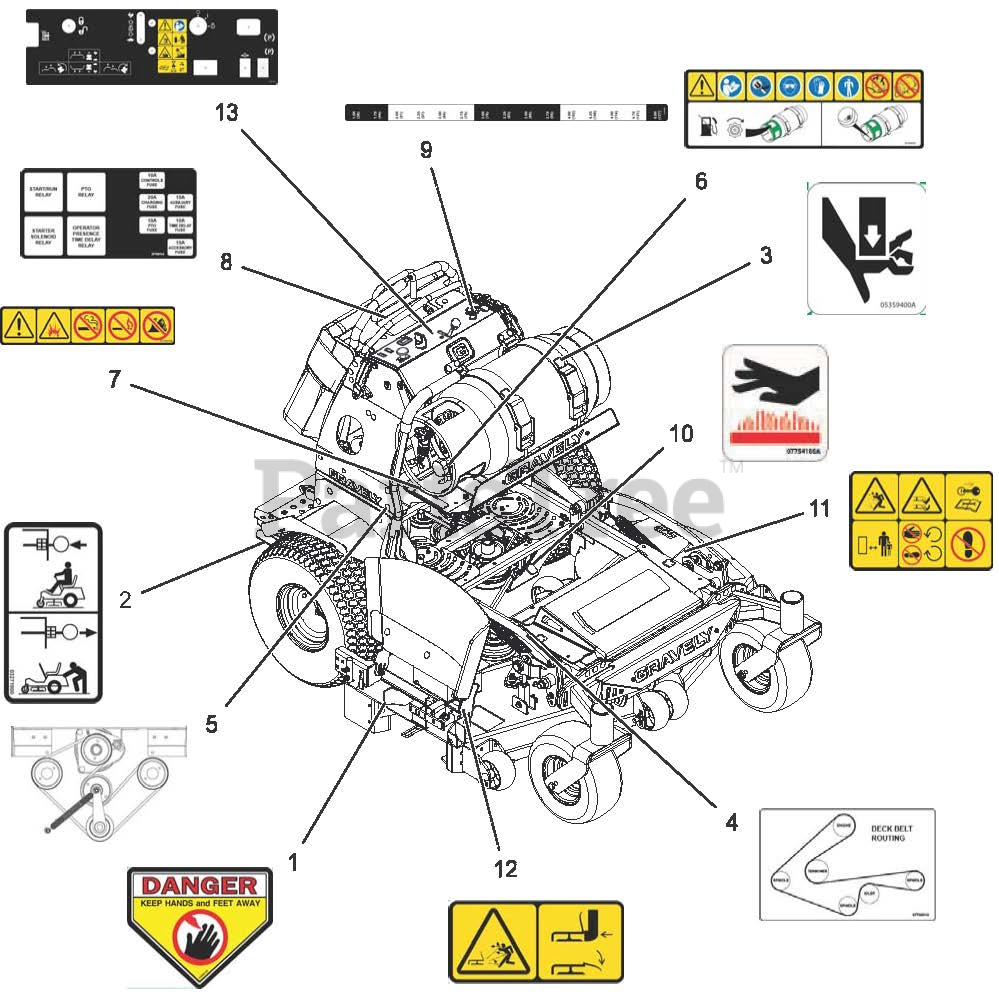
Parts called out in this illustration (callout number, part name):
1	DECAL, DANGER
2	DECAL, TRANSMISSION DISCONNECT
3	DECAL, PINCH POINT
4	DECAL, BELT ROUTING 48/52
5	DECAL, PROSTANCE HYD BELT ROUT
6	DECAL, HORZ.MOWER TANKS ONLY
7	DECAL, LP SAFETY
8	DECAL, FUSE BLOCK
9	DECAL, 48-60 PS HOC DIAL
10	DECAL, HOT SURFACE
11	DECAL, SAFETY - MOWER DECK
12	DECAL, SAFETY - DECK GUARDING
13	DECAL, PS CONTROL PANEL EFI
